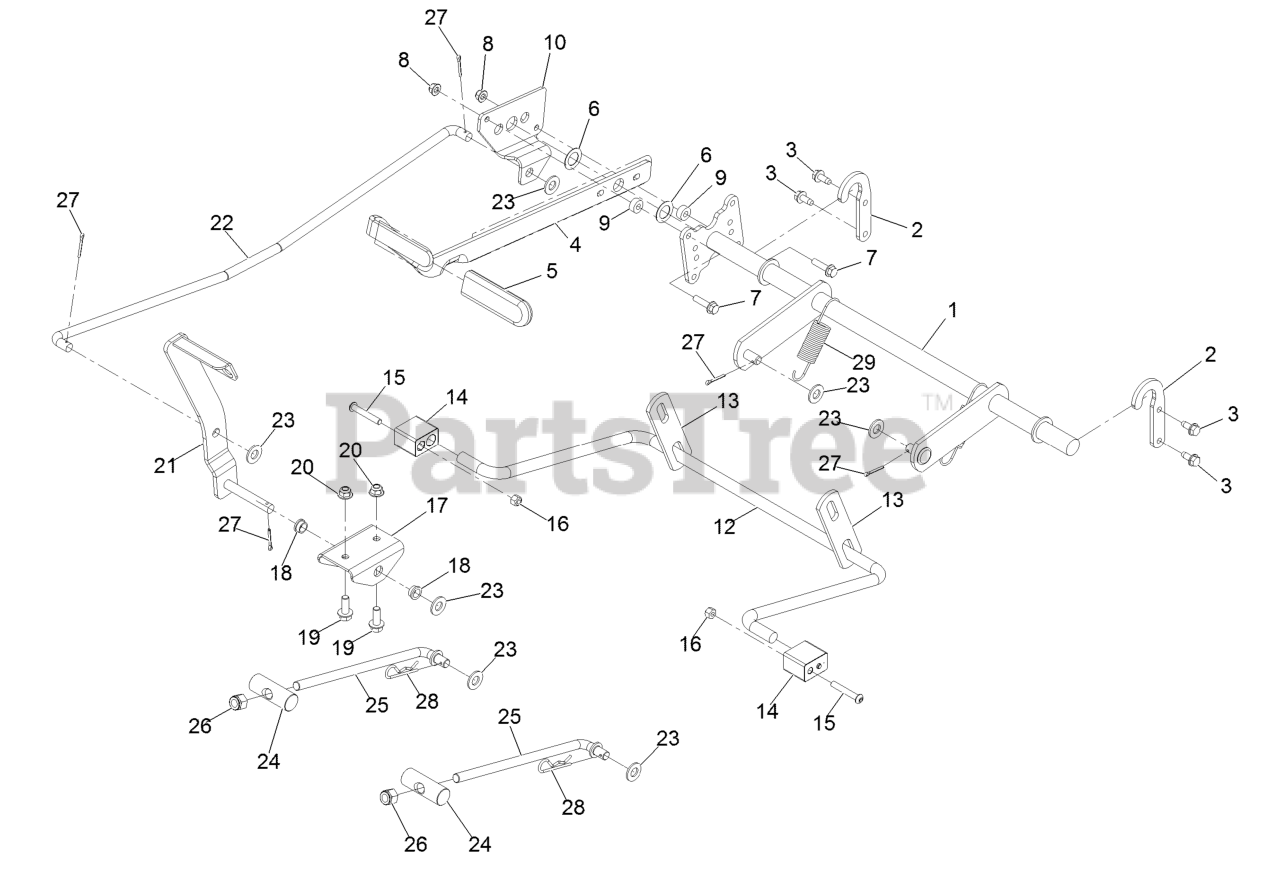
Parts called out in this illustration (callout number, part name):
1	Deck Lift ASM
2	Bracket-Lift
3	Screw-HWH 5/16-18 X 3/4 Tf
4	Handle-Deck Lift
5	Grip-Lever
6	Washer-Thrust
7	Screw-HH Flg 5/16-18 X 1 1/4
8	Nut-Nyloc 5/16-18 Flg
10	Plate-Footlift
12	Arm-Lift, Rear (Wide)
13	Link-Lift
14	Block-Pivot
15	Screw-Button Head 5/16-18 X 2.00
16	Nut-Nyloc 5/16-18
17	Bracket-Footlift
18	Bushing-Flange
19	Screw HHF 3/8-16 X 1
20	Nut-Nyloc 3/8-16 Flg
21	Pedal ASM
22	Rod-Footlift
23	Washer-1/2 SAE
24	Pin-Pivot
25	Rod-Mount, Deck
26	Nut-Nyloc 1/2-20
27	Pin-Cotter 1/8 X 1
28	Hairpin-Cotter
29	Spring, Extension
